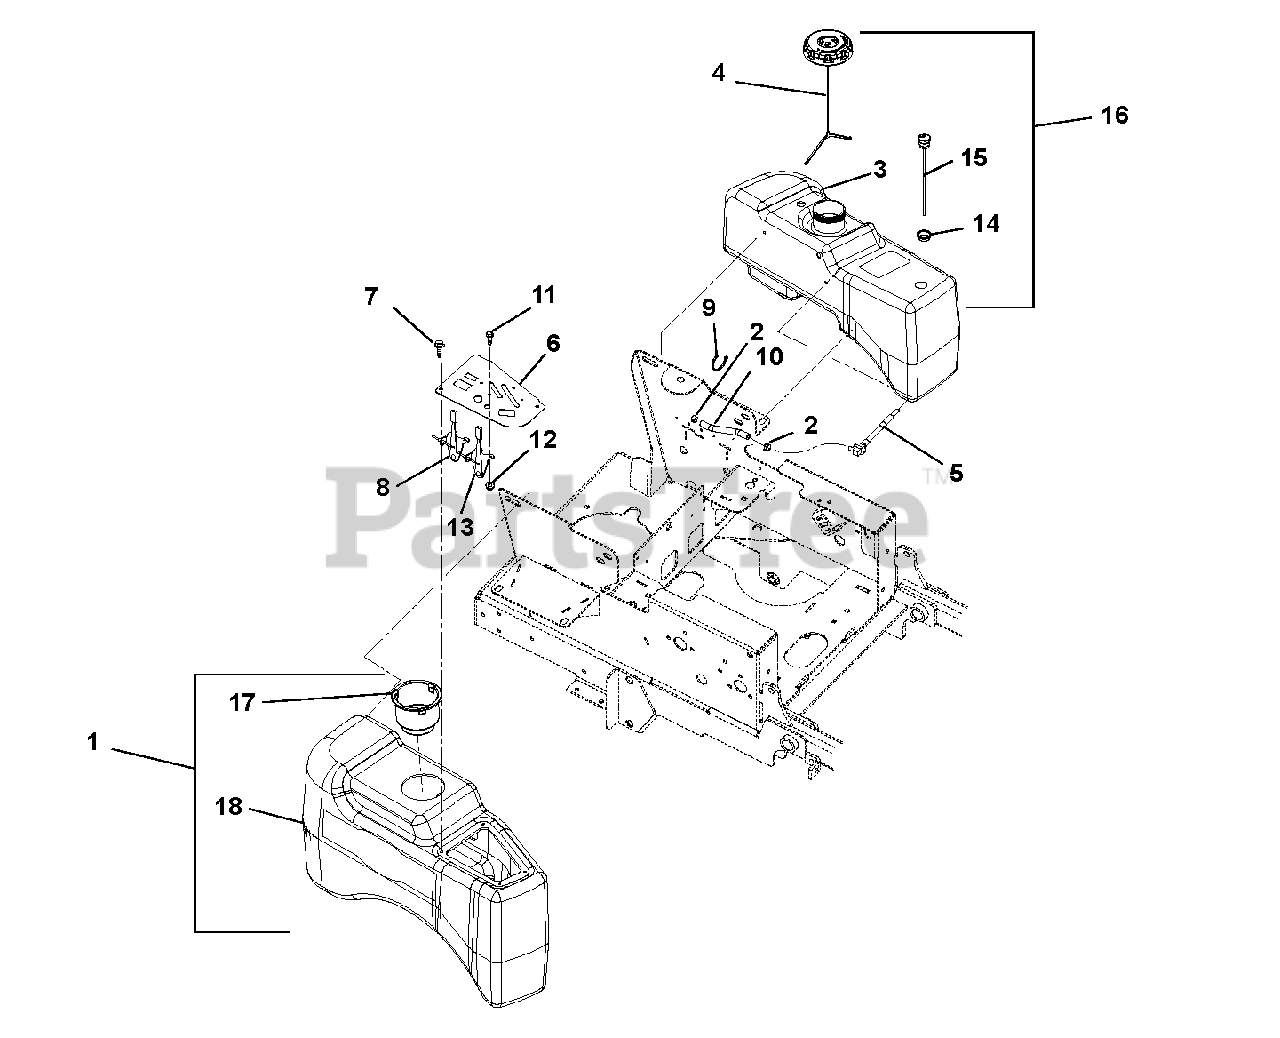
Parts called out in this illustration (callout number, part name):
1	Assembly, Fender with Cupholder (Includes items 17 and 18)
2	Clamp, Fuel Line
3	Tank, Fuel Left Hand
4	Cap, Fuel Vent-in Autolock (991082, 083, 084, 090, 091)
4	Cap, Fuel Non-Vent Autolock (991098, 099, 100, 101)
5	Assembly, Tank Fuel Pick-up
6	Panel, Control
7	Screw, Plastite .25 x 10 x .75 YZ
8	Cable, Control (991082, 083, 084, 090, 098, 099, 100, 101)
8	Cable, Control (991091)
9	Cable Tie
10	Hose, .25 Low-PERM Bulk Gas
11	Screw, Machine 10-24 x .50 Hex Washer Head
12	Nut, Locking Nylon 10-24 with Insert
13	Cable, Throttle Control (991090)
14	Grommet, Fuel Gauge
15	Gauge, Remote Fuel 10.0"
16	Assembly, Fuel Tank (Includes items 3, 4, 5, 14, 15 above and items 1, 2 on page 11)
17	Cupholder
18	Fender
